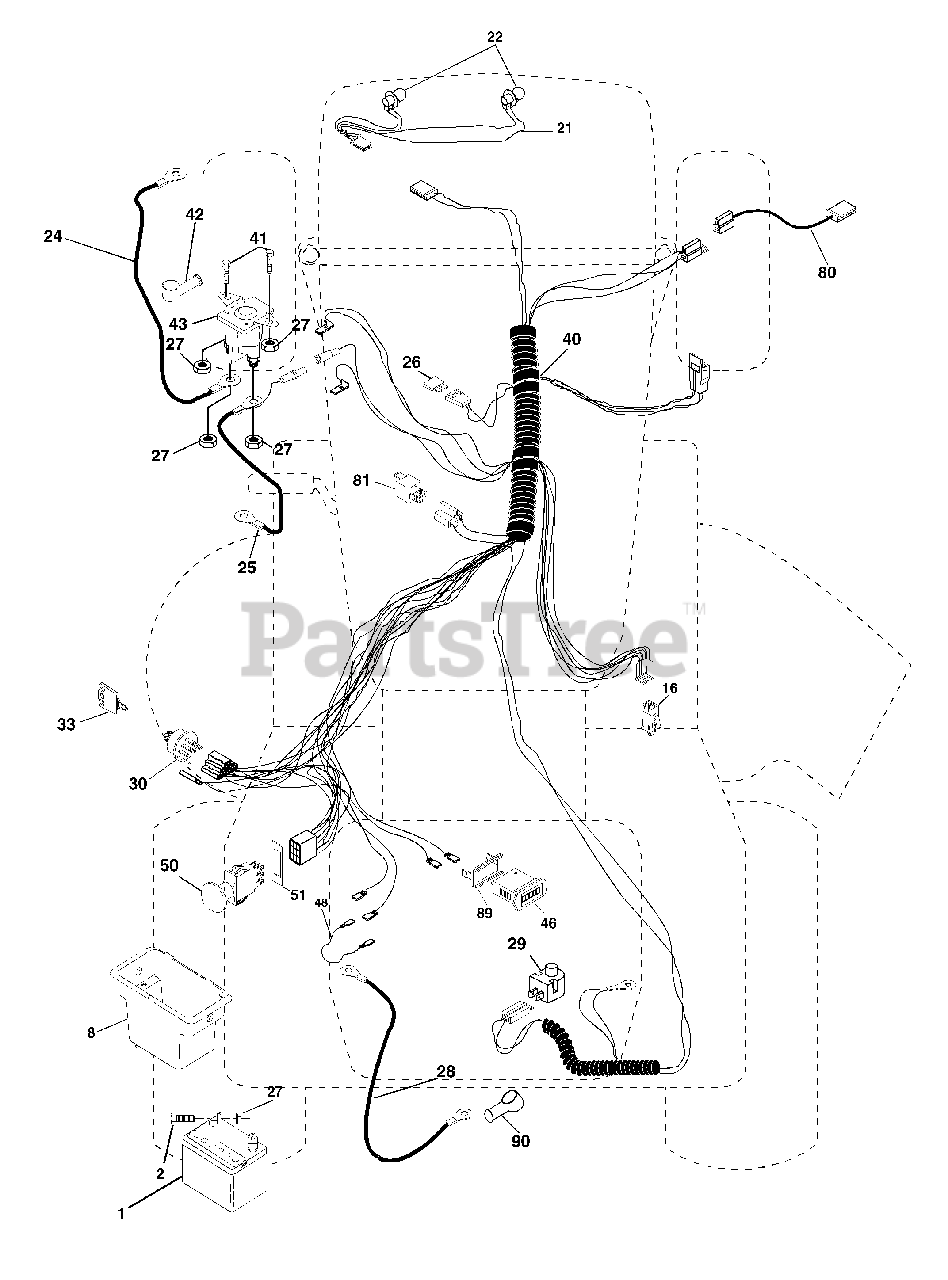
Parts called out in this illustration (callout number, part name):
1	Battery 12 Volt 28 AMP
2	Bolt Hex Hd 1/4-20unc X 3/4
8	Battery Box
16	Switch Interlock Push-In
21	Harness Asm Light W/4152j
22	Bulb Light #1156
24	Cable Battery 6 Ga 11" red
25	Cable Battery 6 Ga 44" red w/16 wire
27	Nut Keps Hex 1/4-20 Unc
28	Cable Ground 6 Ga 12" black
29	Switch Plunger Nc Gray
30	Switch Ign
33	Key Ign Generic
40	Harness Ign.
41	Bolt Blk Fin Hex 1/4 - 20 x 1/2
42	Cover Terminal Red
43	Solenoid
46	Meter Hour
48	Adapter Ammeter
50	Switch PTO
51	Ring Retainer PTO
80	Harness Clutch Evx
81	Relay Asm.
89	Bracket Snap-In Hourmeter
90	Cover Terminal
